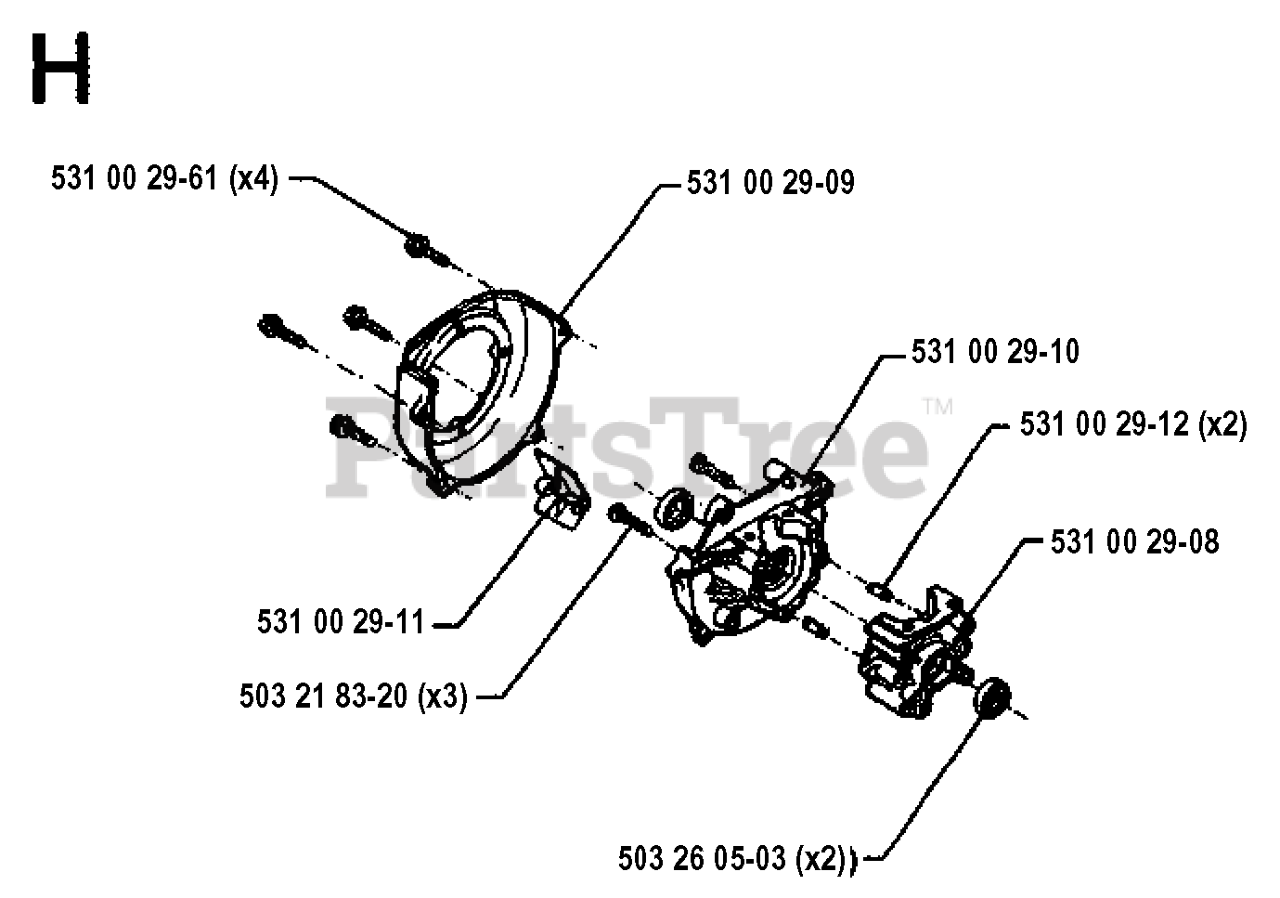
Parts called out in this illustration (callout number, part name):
1	42" DECK KIT
2	RP BOLT 5/16-18 X3/4 ZN/YEL GR
3	BRKT ASM SWAY BAR
4	BRACKET SWAY BAR 42" DECK
5	RETAINER-SPRNG RB
6	REAR SUSP ARM
8	BLADE BOLT
9	LOCKWASHER
10	WASHER.BLADE
11	BLADE.42".MULCH
12	BEARING.BALL.#6204.(MANDREL)
13	SHAFT ASM VENT
14	HOUSING.MANDREL.VENTED (MACHD)
16	STRIPPER
18	BOLT
19	BOLT SHD 5/16-18
20	BAFFLE.VORTEX
21	LOCKNUT
22	STIFFENER BRACKET
23	DEFLECTOR BRACKET
24	CAP-SLEEVE LT
25	SPRING TORSION
26	NUT PUSH M
27	SHIELD DEFLECTOR
28	Washer 11/32 x 5/8 x 16 Ga SD
29	ROD.HINGE
30	SCREW THDROL ROLLING WASHER HD
31	WASHER
32	PULLEY/MANDREL
33	NUT
35	FASTENER.XMAS.TREE
36	FLAT IDLER PULLEY
37	WASHER
44	GUARD MANDREL LH BLACK
45	RETAINER M
46	SCREW.1/4-20X5/8
49	ROLLER ASSY
52	BOLT.SHOULDER.5/16-18
53	ARM
54	HARDENED WASHER
55	ARM IDLER 42" MOWER LT/YT
56	SPACER.RETAINER.MOWER
59	GUARD, BELT
67	KNOB T (3/8 HOLE)
68	BELT V SECONDARY
92	NUT
128	WASHER FELT
129	WASHER
131	BOLT D
142	ARM SPRING BRAKE MOWER
143	BRACKET, ARM IDLER
144	DNO KEEPER.BELT.42".CLUTCH.CBL
145	PULLEY
146	BOLT, CARRIAGE IDLER
147	SPRING EXTENSION
148	IDLER RETURN SPRING
149	SPRING.RETAINER.YELLOW.ZINC
151	BRACKET.CLUTCH.CABLE
152	CLUTCH CABLE 42"
153	WASHER FLAT 3/8"
154	SPRING RETAINER
155	SPRING RETENTION LEVER
156	SPACER.CLUTCH.CABLE
157	ROD CLUTCH CABLE 3/8"
158	SCREW LT
